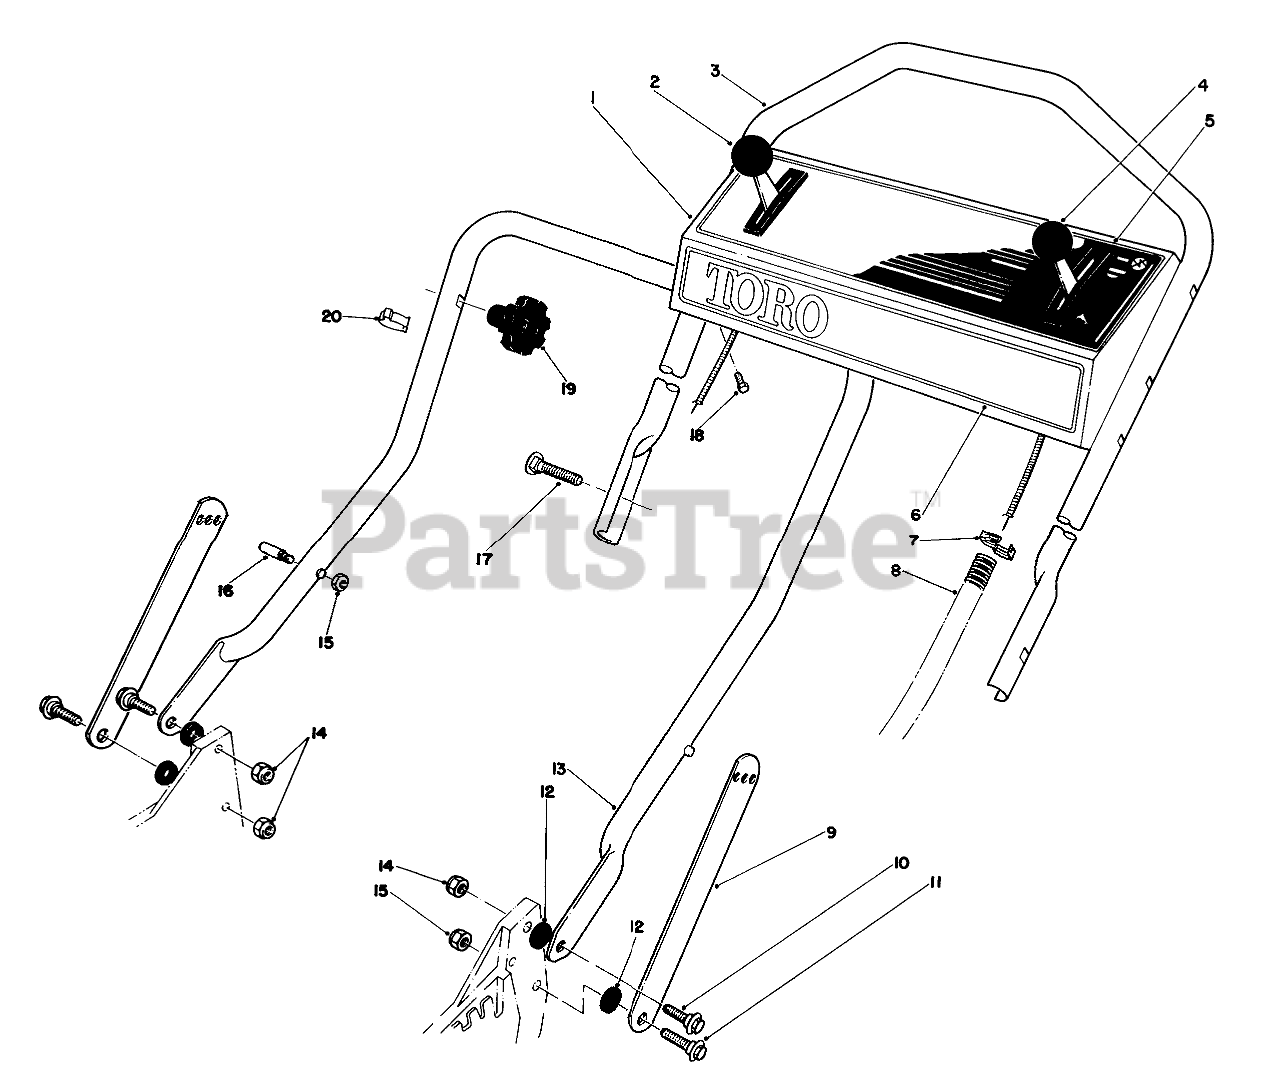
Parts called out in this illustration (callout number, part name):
1	Panel-Control (Incl. Ref. #5)
2	GROUND SPEED CONTROL
3	Handle-Upper
4	Control-Throttle (Bend #5)(Sheath 4. 55-7/8 inches)(Wire 4. 2-1/2 inches)
5	Decal-Instruction Panel
6	Decal-Toro
7	FITTING-RING
8	CONTROL CABLE COVER
9	Handle Latch
10	SCREW-SHOULDER
11	SCREW-SHOULDER
12	SPACER
13	Handle-Lower
14	NUT-LOCK, NI
15	NUT-LOCK, NI
16	HANDLE PIN
17	5/16-18 X 2 HNDLE SCREW
18	SCREW-HWHTF
20	BOWDEN CLIP
